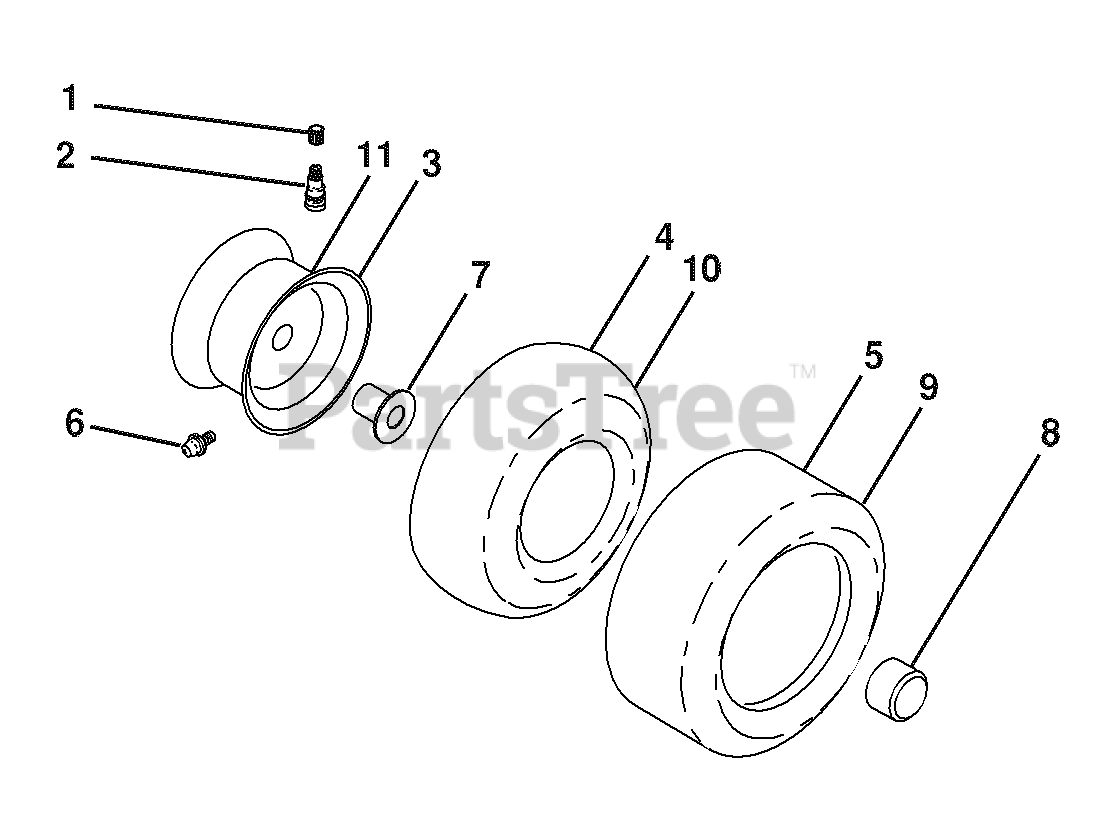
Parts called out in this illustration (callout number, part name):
1	Cap Valve Tire
2	Stem Valve
3	Rim Front Service
4	Tube Front
5	Tire Front 15 x 6.0-6 Service
6	Fitting Grease
7	Bearing Flange
8	Cap Axle Blk 1 50 x 1 00
9	Tire R T 18 x 9.5-8 Service
10	Tube Rear
11	Rim Asm 8" rear Service
11	Sealant, Tire
